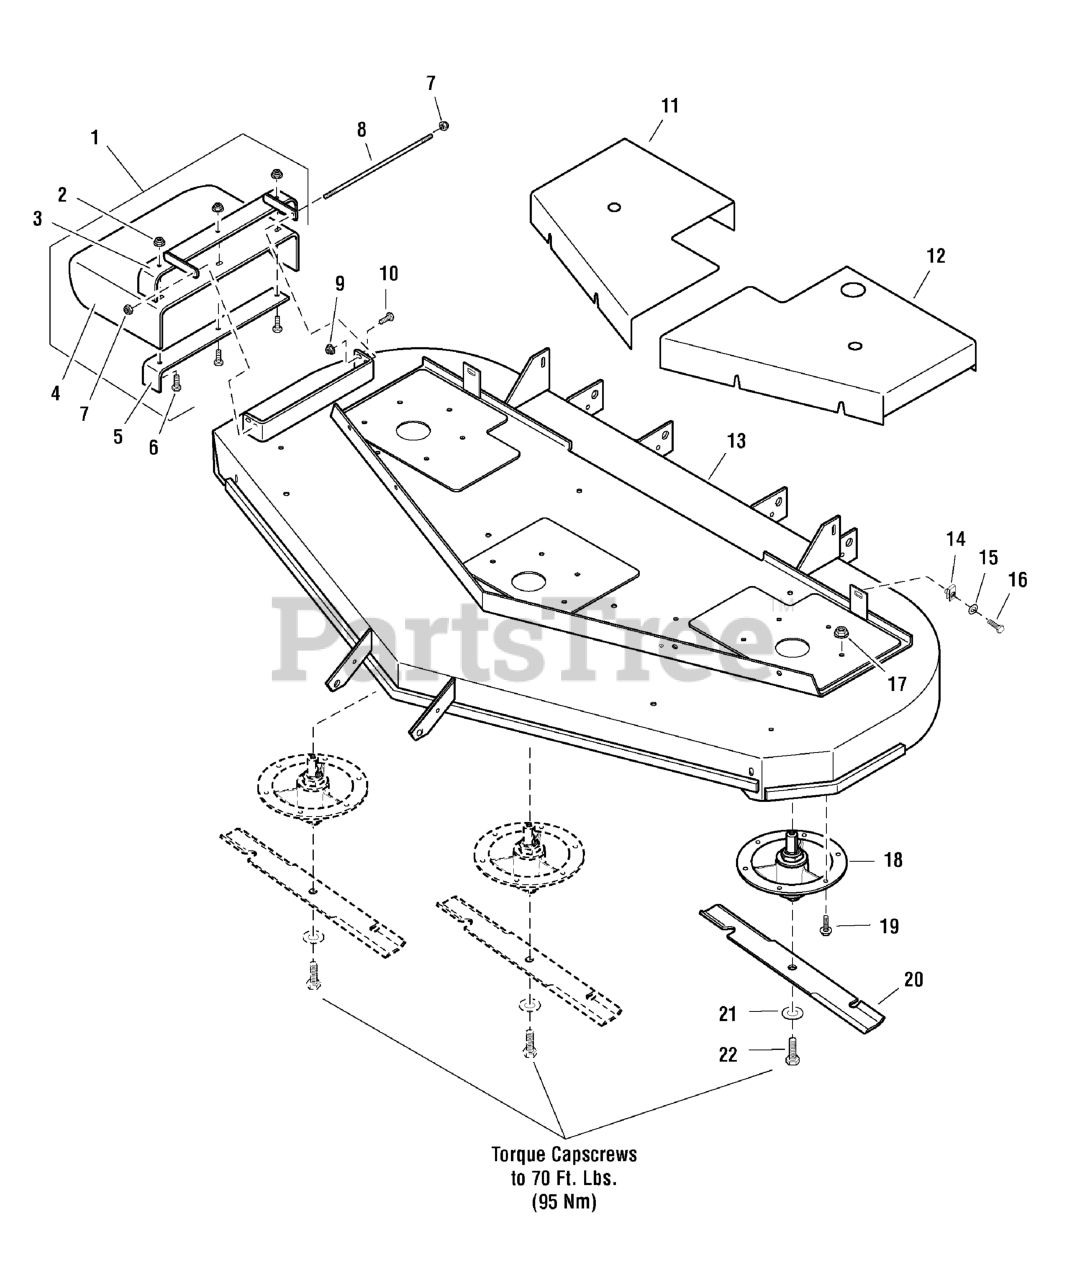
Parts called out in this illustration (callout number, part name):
1	RUBBER CHUTE ASSEMBLY, Complete
2	NUT, 3/8-16 Hex Nylock Flange
3	CHUTE FRAME
4	CHUTE, DISCHARGE, RUBBER, 61/72, BENT
5	CHUTE SUPPORT
6	BOLT, 3/8-16 X 1-1/4" GD5 CZ
7	NUT, 5/16-24 HEX NYLON LOCK
8	CHUTE MOUNT ROD
9	NUT, 5/16-18 Hex Nylock Flange
10	BOLT, 5/16-18 X 3/4 GD5
11	SPINDLE COVER - RH
12	SPINDLE COVER - LH
14	BODY CLIP, 5/16-18-7GA MATERIAL
15	WASHER, 5/16" SAE
16	BOLT, 5/16-18 X 3/4 GD5
17	NUT, 3/8-16 Hex Nylock Flange
18	SPINDLE ASSEMBLY
19	BOLT, Flange Head, 3/8-16 x 1-1/4
20	BLADE, 25" (SET OF THREE)
21	WASHER, 5/8" GRADE 8, YZ
22	BOLT, 5/8-11 X 1-3/4 GD8
